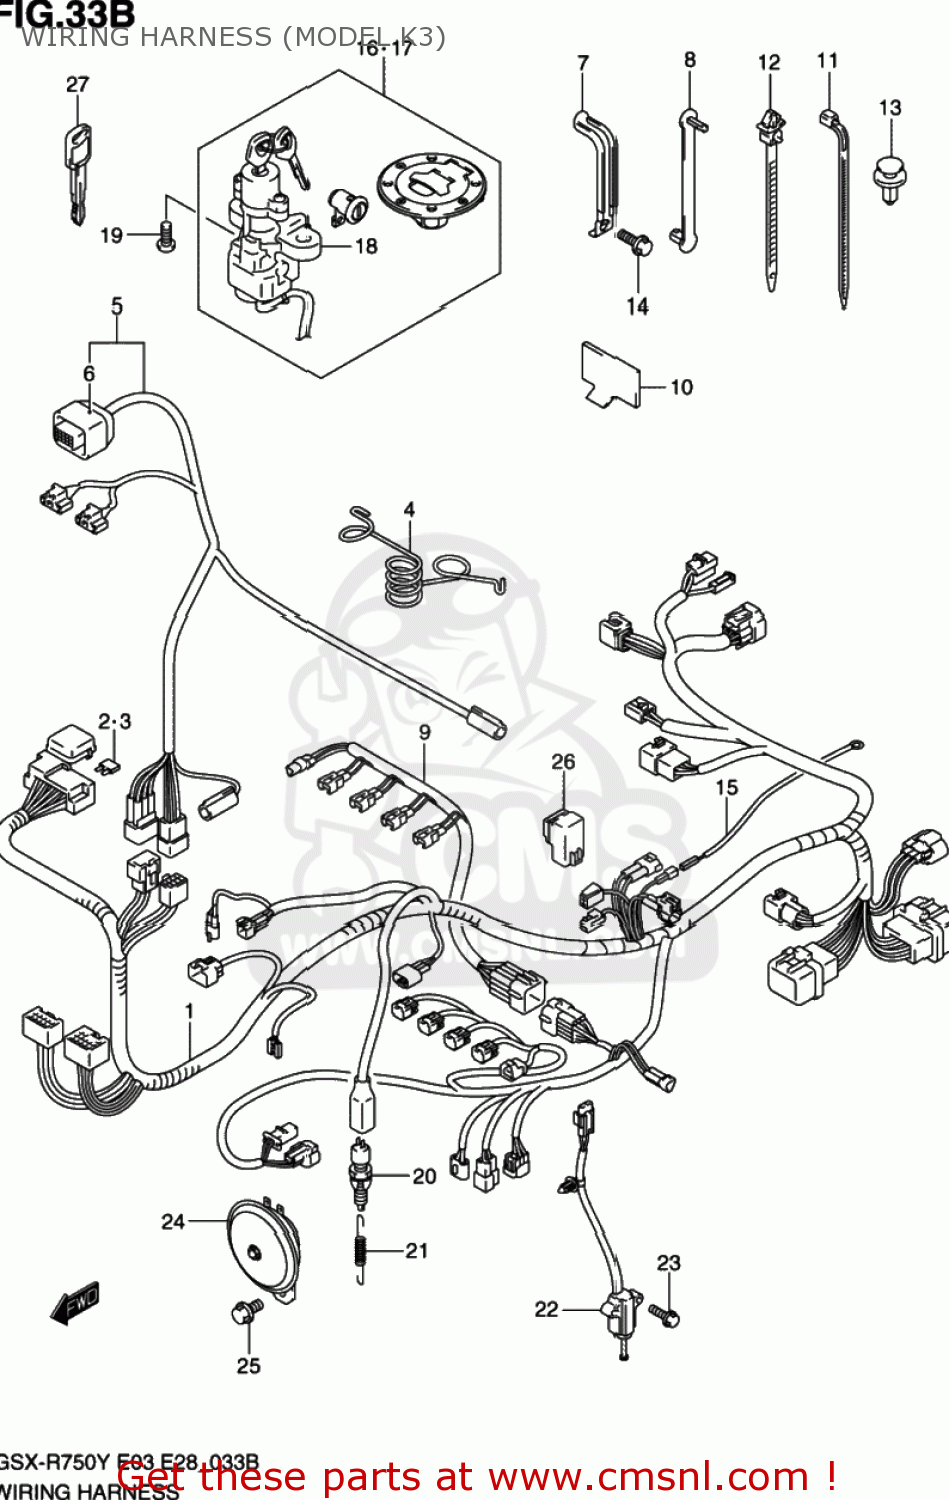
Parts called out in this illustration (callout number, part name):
1	HARNESS,WIRING NO.1
2	FUSE(10A)
3	FUSE(15A)
4	GUIDE,WIRING HARNESS
5	HARNESS,WIRING NO.2
6	COVER,SPEEDOMETER COUPLER
7	CLAMP
8	CLAMP(L:63)
9	WIRE,INJECTION LEAD
10	PROTECTOR,WIRING HARNESS
11	CLAMP(L:65)
12	CLAMP(L:90)
13	CLAMP(L:120)
14	BOLT
15	WIRE,OIL PRESSURE SWITCH LEAD
16	LOCK SET
17	LOCK SET
18	LOCK ASSY,STEERING
19	BOLT(8X20)
20	SWITCH ASSY,STOP LAMP
21	SPRING
22	SWITCH ASSY,SIDE STAND
23	BOLT
24	HORN ASSY
25	BOLT
26	RELAY ASSY
27	KEY,BLANK
